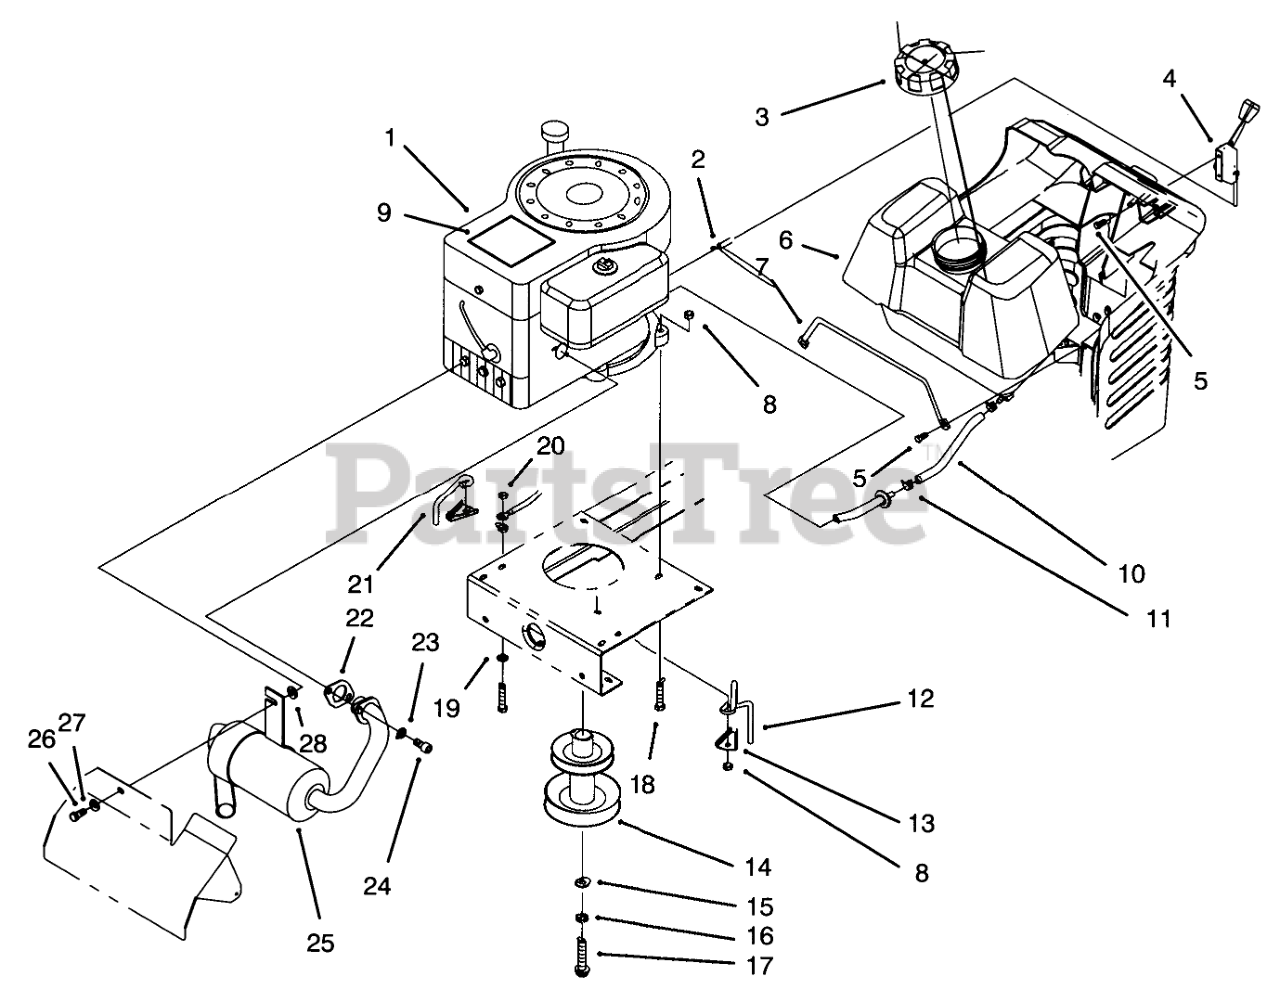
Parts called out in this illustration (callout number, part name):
1	Engine-10 H.P. (Model No. 71140 Only)
2	THROTTLE CABLE ASM
3	GAS CAP ASM
4	THROTTLE CONTROL ASM
5	SCREW-SPECIAL
6	GAS TANK ASM
7	GAS TANK ROD
8	NUT-LOCK, NI
9	DECAL - ENGINE
10	HOSE-FUEL
11	CLAMP-HOSE
12	GUIDE-BELT, LH
13	ANCHOR-GUIDE, BELT
14	PULLEY-ENGINE
15	WASHER-FLAT
16	WASHER-LOCK
17	SCREW-HH
18	SCREW-HH
19	WASHER-LOCK
20	NUT-KEPS
21	GUIDE-BELT, RH
22	GASKET-EXHAUST
23	WASHER-LOCK
24	SCREW-HSH
25	MUFFLER
26	SCREW-HH
27	WASHER-LOCK
28	SPACER-PIN, MOUNTING
